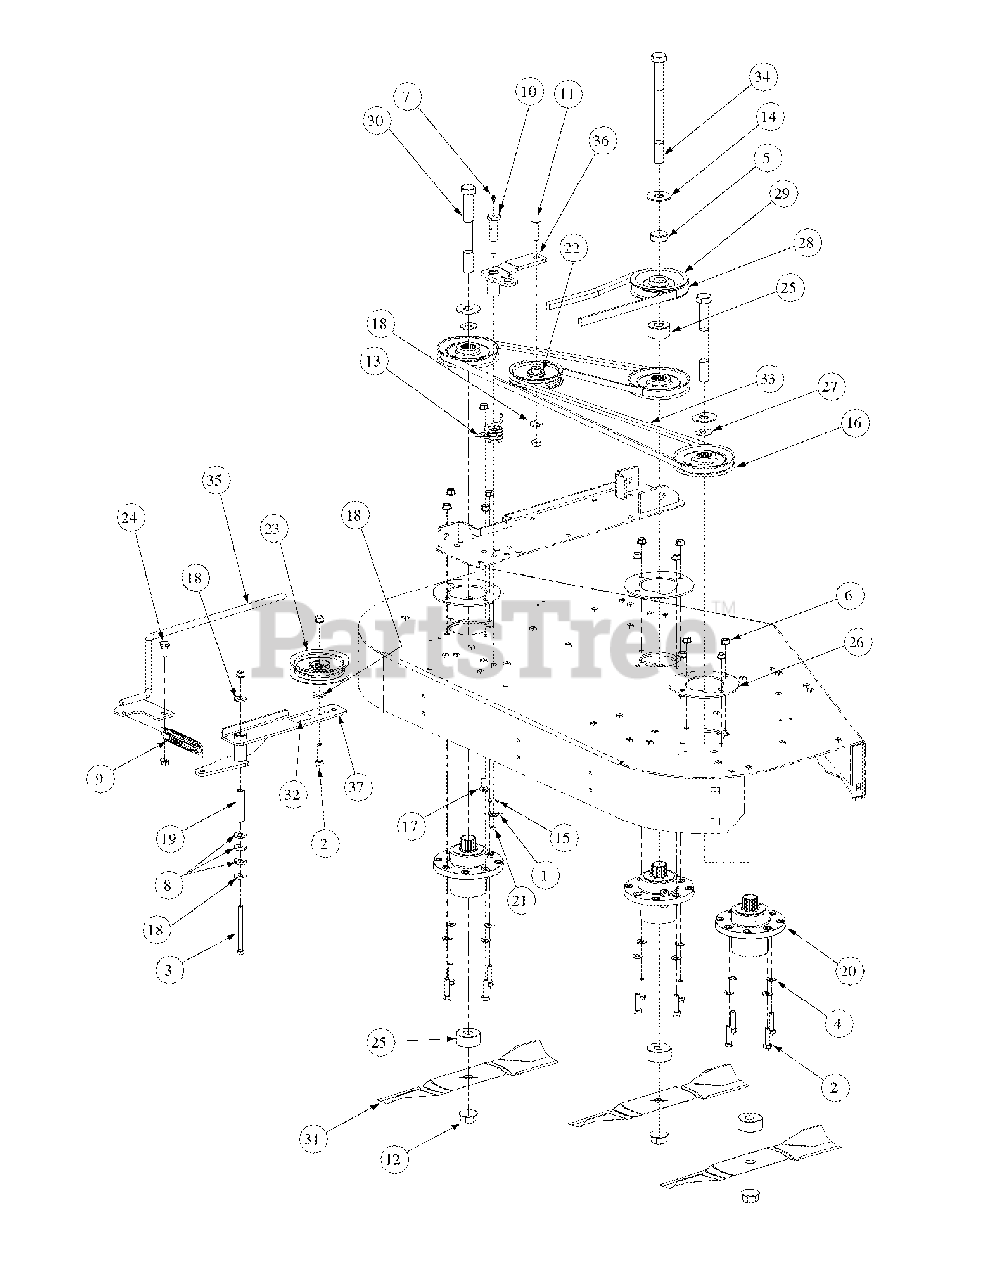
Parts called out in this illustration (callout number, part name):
1	Lock Washer, 7/16
2	Hex Cap Screw, 3/8-16 x 1-1/4
3	Hex Cap Screw, 3/8-16, 4.00
4	Flat Washer, 3/8
6	Hex Nut, Flange Lock, 3/8-16
7	Grease Fitting, 1/4-28 x 3/16
8	Idler Washer
9	Spring Extension, 1.0 OD x 5.125
10	Shoulder Screw, 7/16-14
11	Hex Carriage Screw, 3/8-16, 1.75
12	Hex Flange Nut, 3/4-16
13	Torsion Idler Spring
14	Flat Washer, .781 ID, 2.00 OD, .105
15	Flat Washer, .469 ID, .875 OD, .105
16	V-Pulley, 5.00 OD
17	Carriage Bolt, 3/8-16 x 1
18	Flat Washer, .406 ID, 1.0 OD, .105
19	Spacer, .39 ID x .625 OD x 2.75
20	Aluminum Spindle Assembly
21	Hex Nut, 7/16-14
22	Flat Pulley
23	Idler Pulley, 4.06 OD w/Deep Flange
24	Shoulder Screw, .50 x .27 Lg., 3/8-16
25	Spacer, .760 ID x 2.000 OD x 1.1
26	Spindle, Aluminum Cast Support Plate
27	Spacer, .812 ID x .218 LG
28	V-Belt, B Section x 83.2
29	V-Pulley, 4.75 OD
30	Hex Cap Screw, 3/4-16, 7.00
31	Blade, 17.0, Hi-Lift, 0.756 ID
32	Decal, Idler Location
33	V-Belt, A Section x 105.3
34	Hex Cap Screw, 3/4-16, 9.00
35	Spring Tension Rod Assembly
36	Idler Arm Assembly, Deck Spindle
37	Idler Arm Assembly, Flat Top Bearing
